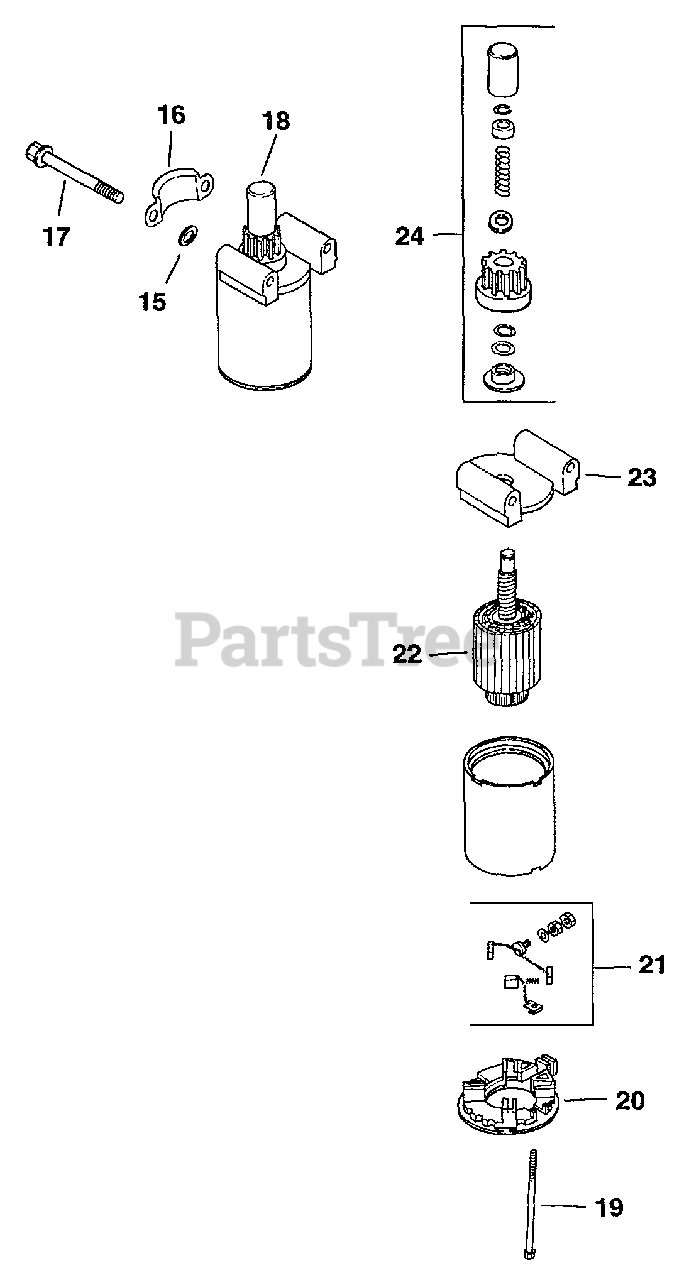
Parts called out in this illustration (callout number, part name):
15	WASHER, FLAT 11/32"
16	COVER, PINION
17	SCREW - USE M-839070
19	SCREW - (#DSC)
20	COMMUTATOR, END CAP
21	KIT, BRUSH & SPRING - DISCONTINUED
22	ARMATURE ASSY - DISCONTINUED
24	KIT, DRIVE
